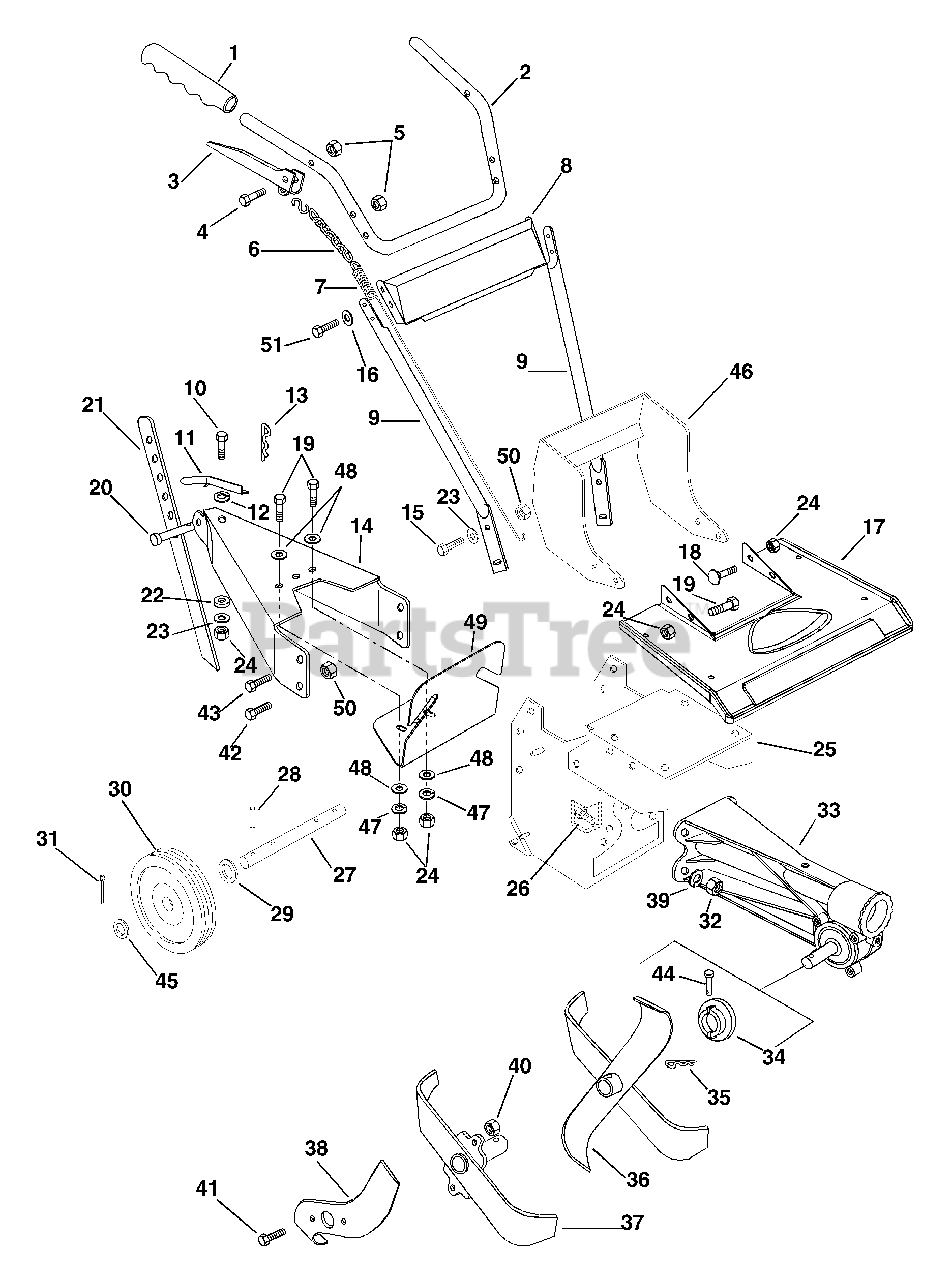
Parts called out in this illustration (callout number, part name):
1	GRIP
2	HANDLEBAR WITH DECALS - FT524
3	HANDLE, CLUTCH
4	@BLT-HEX .25-20X1.50 GR5 YWZC
5	@NUT-LK-CTR .25-20 YWZC
6	CLUTCH CHAIN
7	SG-TENS .080X.25X31.6 WLD 35
8	HANDLEBAR PANEL
9	LOWER HANDLE BAR
10	@BLT-HEX .38-16X.75 GR5 YWZC
11	RETAINER CLIP
12	WAVE WASHER .531X.781X.125FH
13	PIN-HAIR-EXT .12X.31X2.37 YWZC
14	DEPTH STICK HOLDER
15	@BLT-HEX .38-16X1.00 GR5 YWZC
16	@WSHR-FL-STL.281X.62X.065 YWZC
17	TINE HOOD
18	@BLT-RDHDSQNK .31-18X.75 G5YZ
19	@BLT-HEX .31-18X.75 GR5 YWZC
20	CLEVIS PIN .437/.431X1.50 YWZC
21	DEPTH STICK
22	SPACER BUSHING .5 X .32 X .21
23	@WSHR-FL-STL.38X.875X.083 YWZC
24	@NUT-LK-CTR .31-18 YWZC
25	FRAME
26	@BLT-HEX .38-16X1.25 GR5 YWZC
27	AXLE ROD YWZC
28	PIN-ROLL .125X1.38
29	SPACER .76 X .51 X .56
31	@PIN-CTR .12X1.25 EXTPRSQCT YZ
32	@NUT-HEX .38-16 YWZC
33	GEAR CASE - CAST IRON
34	DUST CAP
35	PIN-HAIR INT .08X.38X1.42 YWZC
36	RH INNER TINE SPOOL
37	LH OUTER TINE SPOOL
38	TURBO-TINE
39	@WSHR-LK .38X.094 REG YWZC
40	@NUT-LK-CTR .44-14 YWZC
41	@BLT-HEX .44-14X1.00 GR5 YWZC
42	@BLT-HEX .38-16X.75 GR5 YWZC
43	BLT-HEX .38-16X1.50 PL GR5
44	CLEVIS PIN
45	@WSHR-FL-STL.531X1.06X.095YWZC
47	@WSHR-LK .31X.078 REG YWZC
48	@WSHR-FL-STL.344X.688X.065YWZC
49	BRACKET, BELT GUARD
50	@NUT-LK-CTR .38-16 YWZC
51	@BLT-HEX .25-20X1.75 GR5 YWZC
